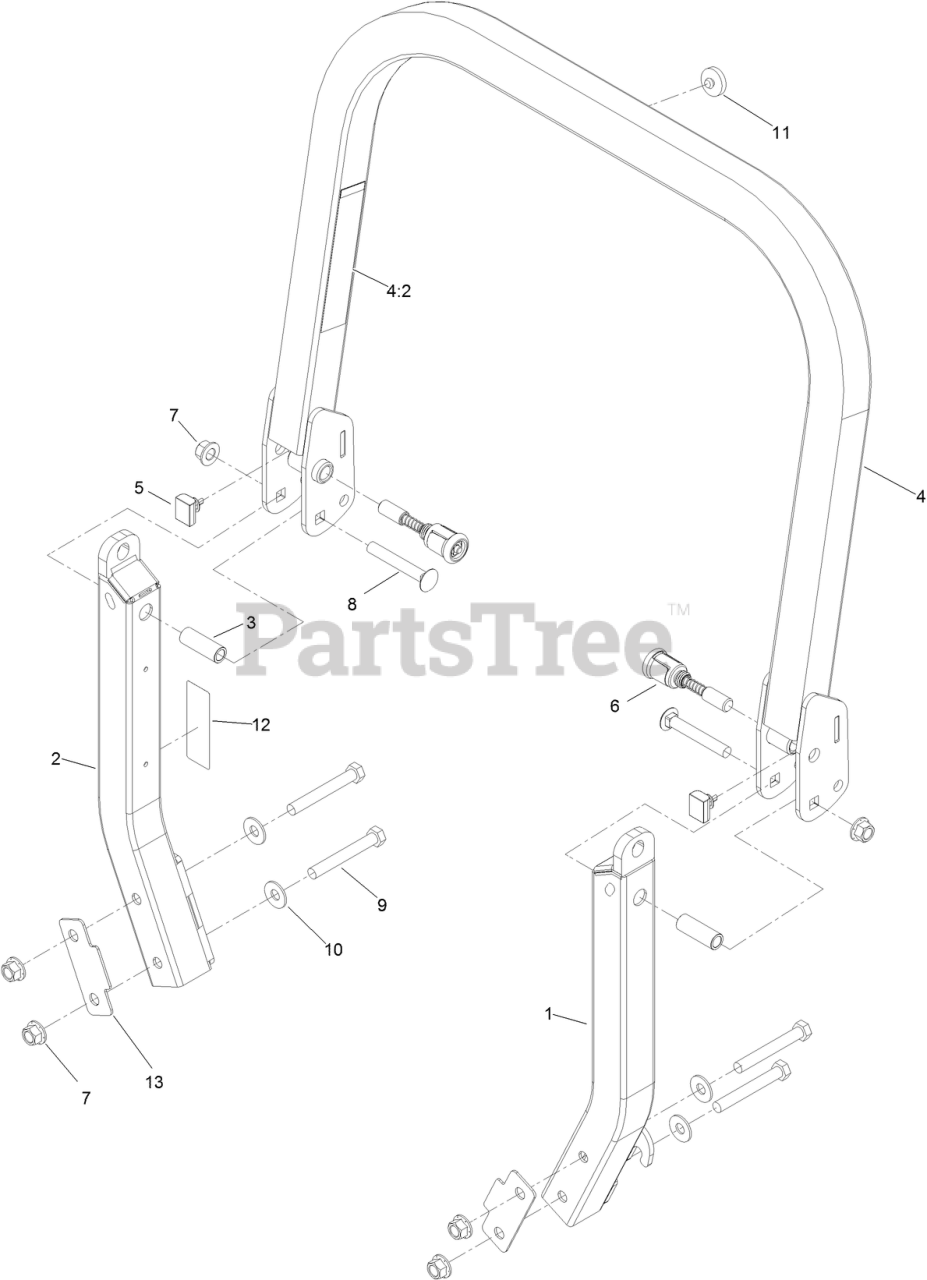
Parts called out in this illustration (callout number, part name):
1	LEG-ROPS, LH
2	LEG-ROPS, RH
3	SPACER
4	UPPER ROPS ASM
4:2	DECAL-WARNING
5	BUMPER-ROPS
6	PIN-SPRING
7	NUT-LOCK
8	SCREW-CARR
9	SCREW-HH
10	WASHER-SPRING
11	BUMPER-PUSH-IN, RUBBER
12	DECAL-CAUTION, FUEL VENT
13	SPACER
